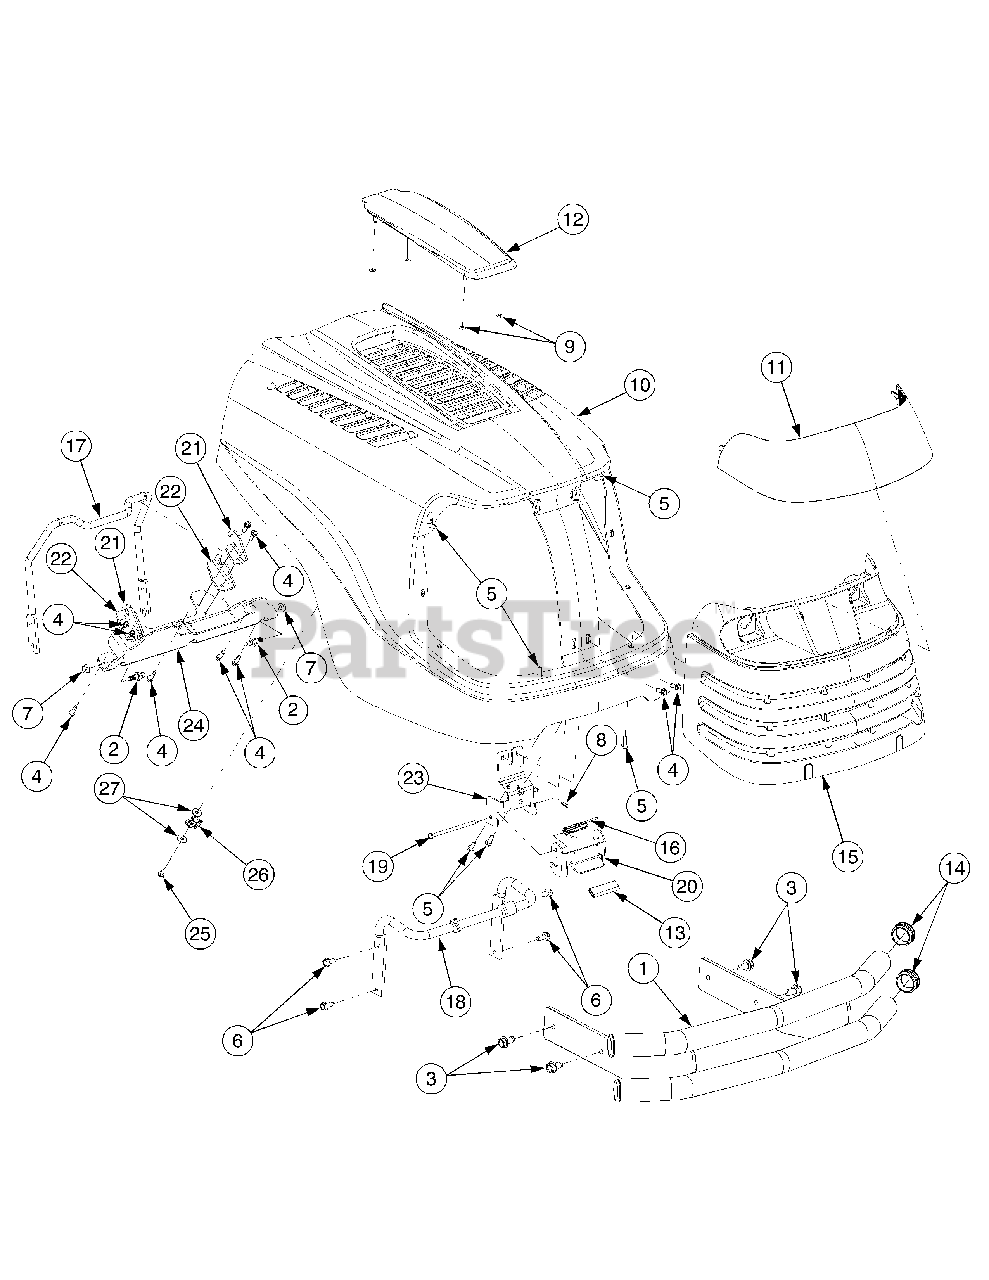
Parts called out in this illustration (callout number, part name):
3	Screw, Hx Washer Hd Tapp 3/8-16 x.750
4	Screw, Hx Washer Hd Tapp 1/4-20 x .750
5	Screw, 1/4-15 x.750
6	Screw, Hx Washer Hd Tapp 5/16- 18 x.750
7	Nut, Flange Lock, 5/16-18 GR5
8	Pin, Cotter,.072 Dia. x 1.13
9	Nut, Push, .25 ID x .50 OD
10	Hood, Service Kit
10	Hood
11	Lens
12	Cover, Hood
13	Vinyl Strip, 2.5"
14	Cap, Bumper
15	Grill
16	Latch Spring
17	Hood Pivot Rod
18	Hood Latch Rod
19	Rod,.250 Dia. x 4.55
20	Latch Pivot Bracket
21	Upper Pivot Bracket
22	Hood Pivot Bracket
23	Latch Plate
26	Clamp, 9/16
27	Washer, Flat, .194 x .62 x .063
